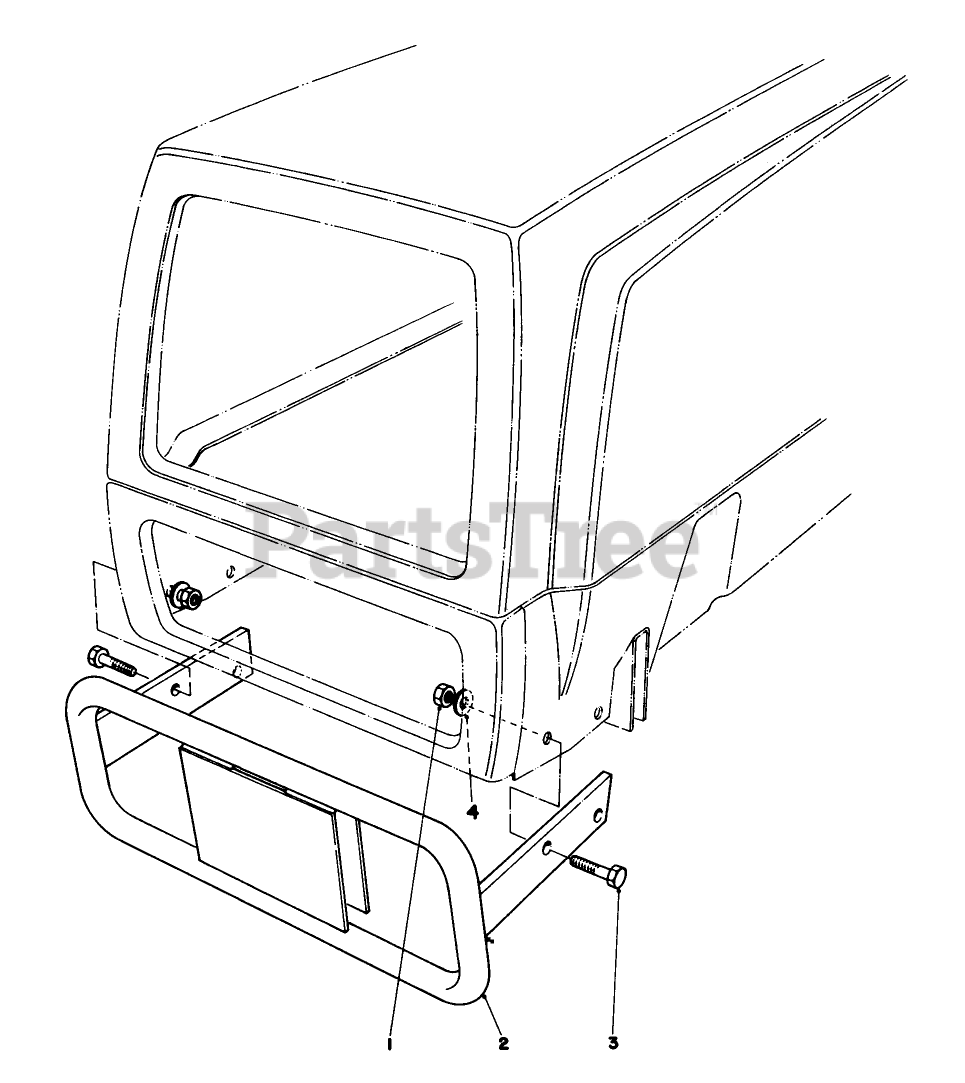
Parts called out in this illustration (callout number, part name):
1	NUT-LOCK, CONE
2	Bumper W.A.
3	SCREW-HH
4	WASHER-PLAIN
